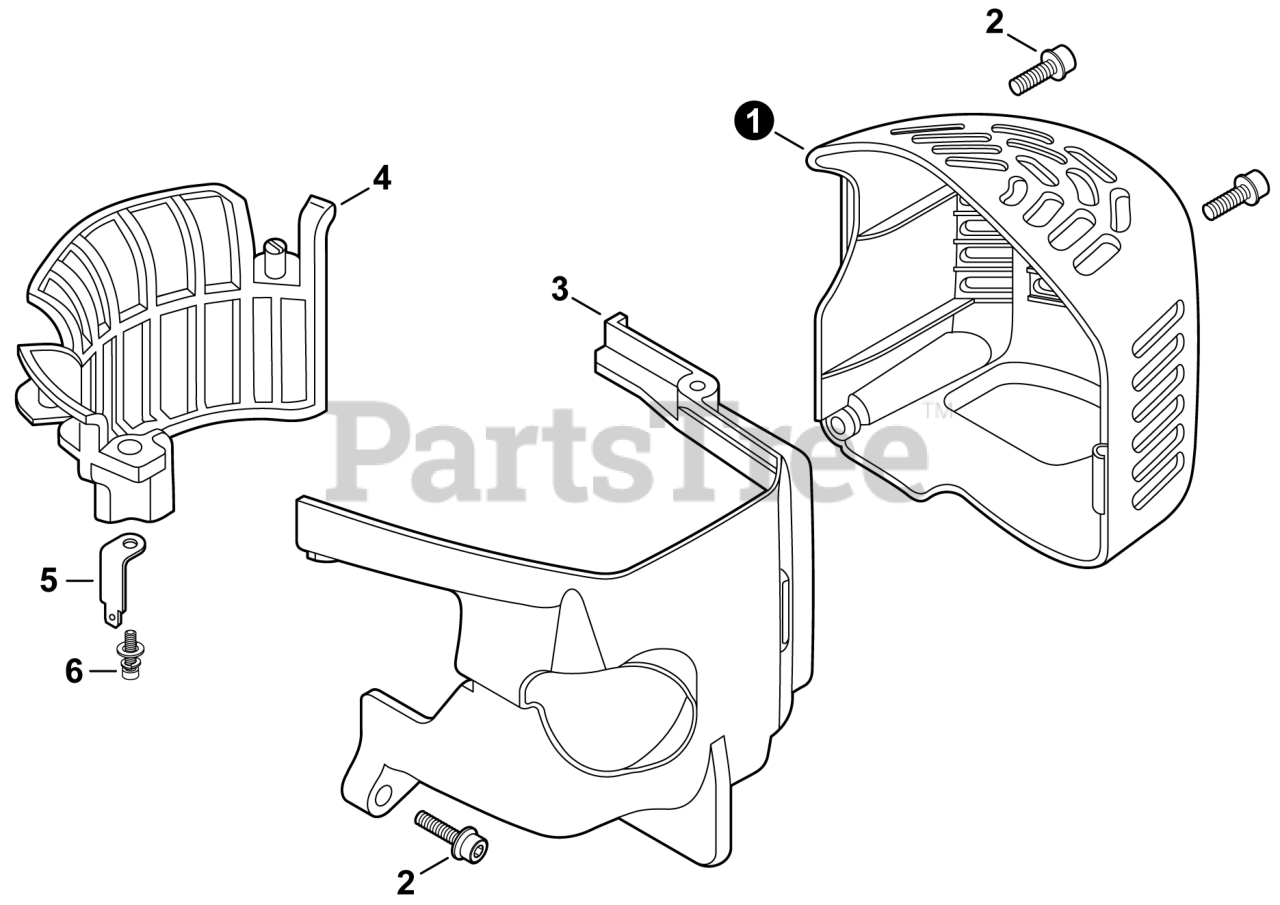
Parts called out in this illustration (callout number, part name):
1	COVER, MUFFLER
2	BOLT 5x16
3	COVER, ENGINE
4	SHIELD, DEBRIS
5	CONNECTOR
6	BOLT 5x16
